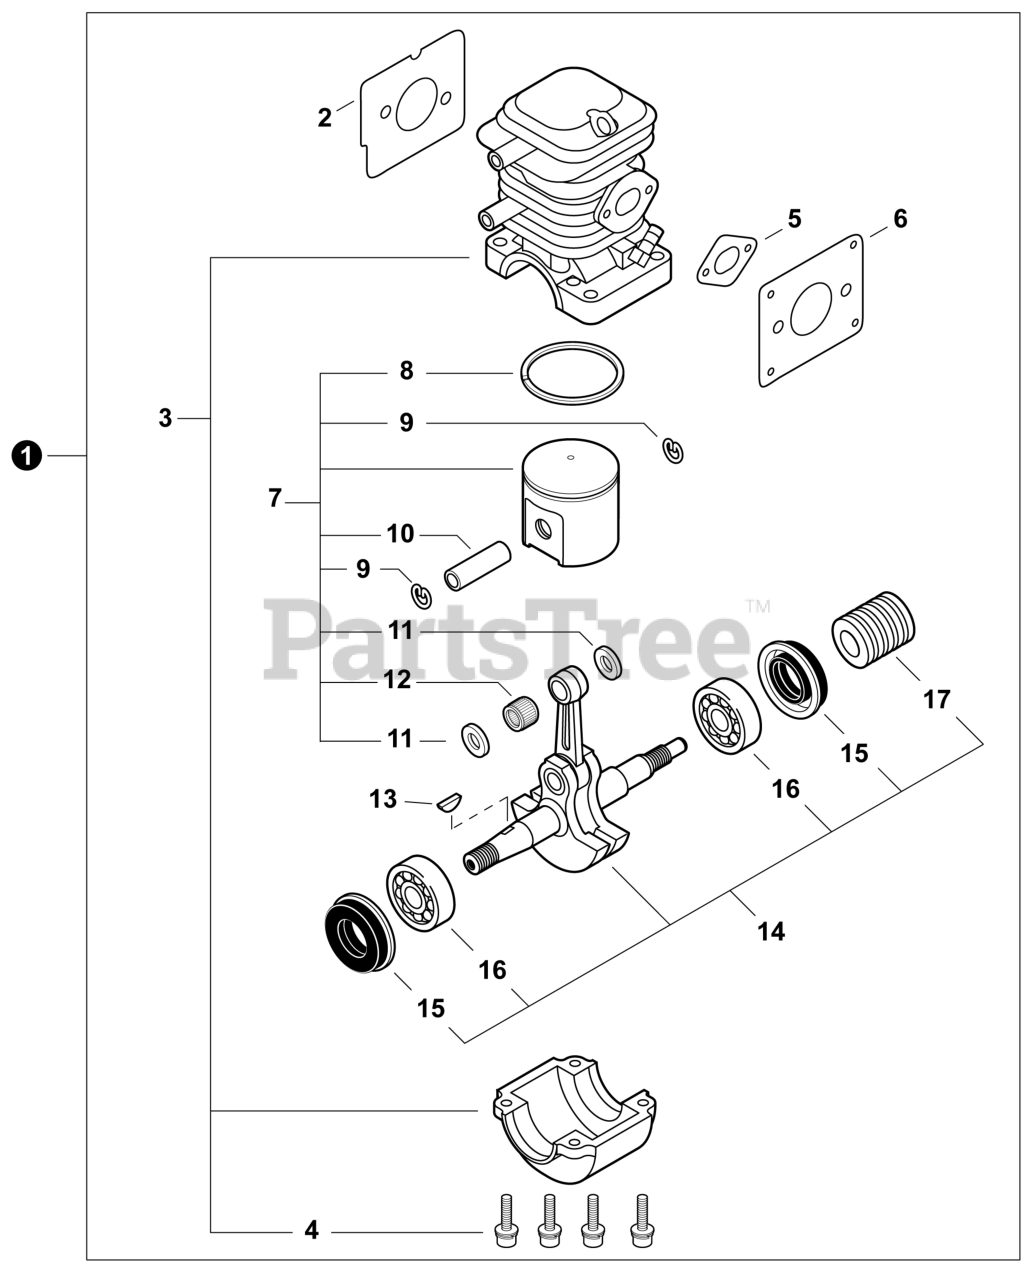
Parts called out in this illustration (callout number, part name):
1	SHORT BLOCK
2	GASKET, EXHAUST
3	CRANKCASE KIT
4	BOLT 5×22
5	GASKET, INTAKE
6	GASKET, INTAKE
7	PISTON KIT
8	RING, PISTON
9	RING, SNAP
10	PIN, PISTON
11	WASHER, THRUST
12	BEARING, NEEDLE 9
13	KEY, WOODRUFF
14	CRANKSHAFT ASSY
15	SEAL, OIL 12
16	BEARING, BALL 6201
17	GEAR, WORM
